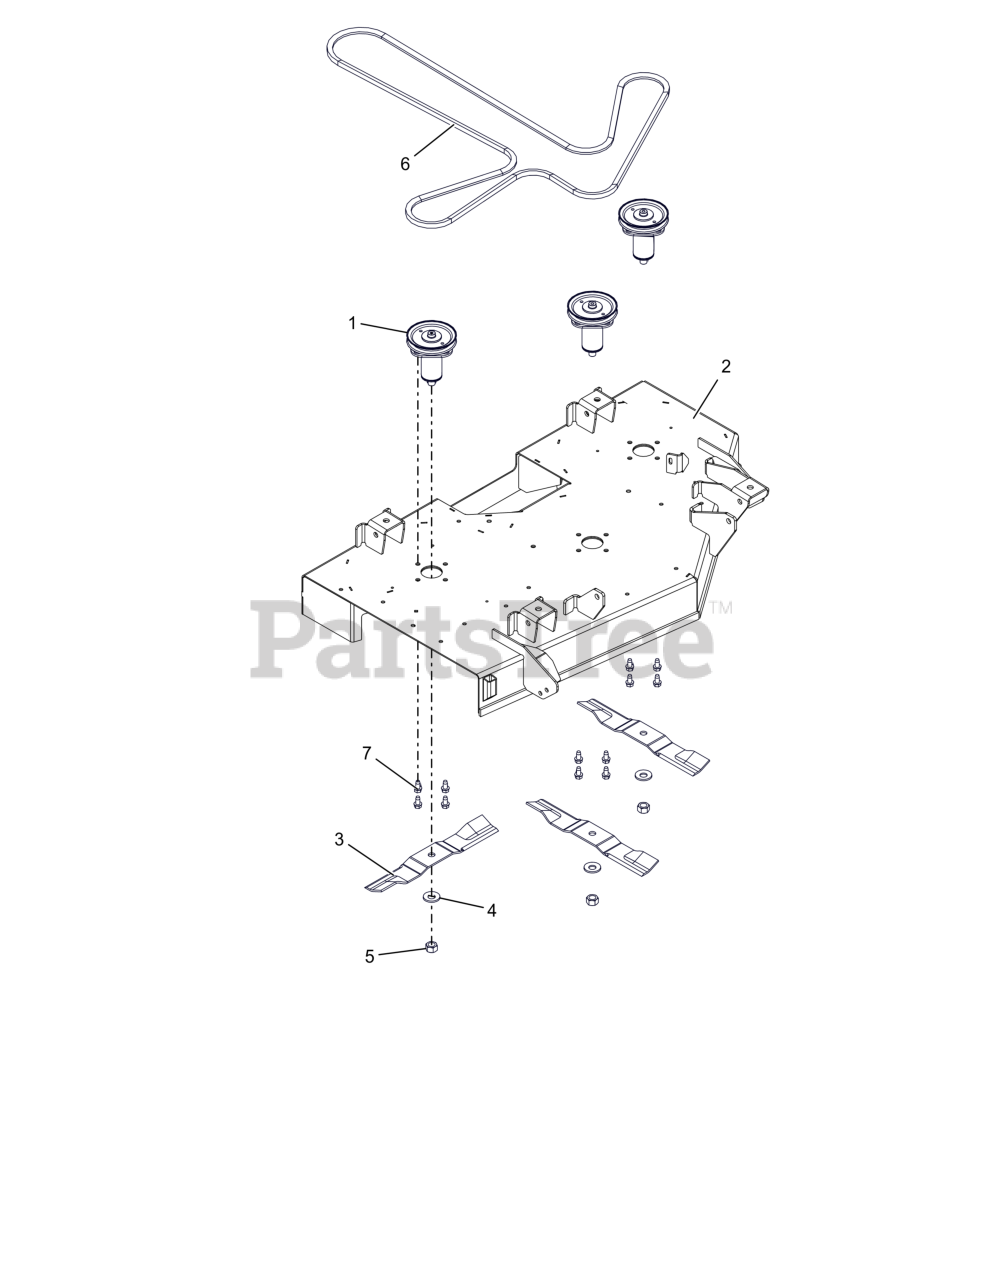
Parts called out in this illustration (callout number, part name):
1	KIT, DECK SPINDLE ASM-IKON-ZTX
2	KIT, 42" GRAVELY DECK W/DECALS
3	BLADE, MOWER 15.00"
4	WSHR-BLVL .669X1.535X.138
5	NUT-STD .625-18 ZCC
6	V-BELT, 4L-WRAPPED
7	SCR,TAP .375-16X.75 HWH TR ZCC
